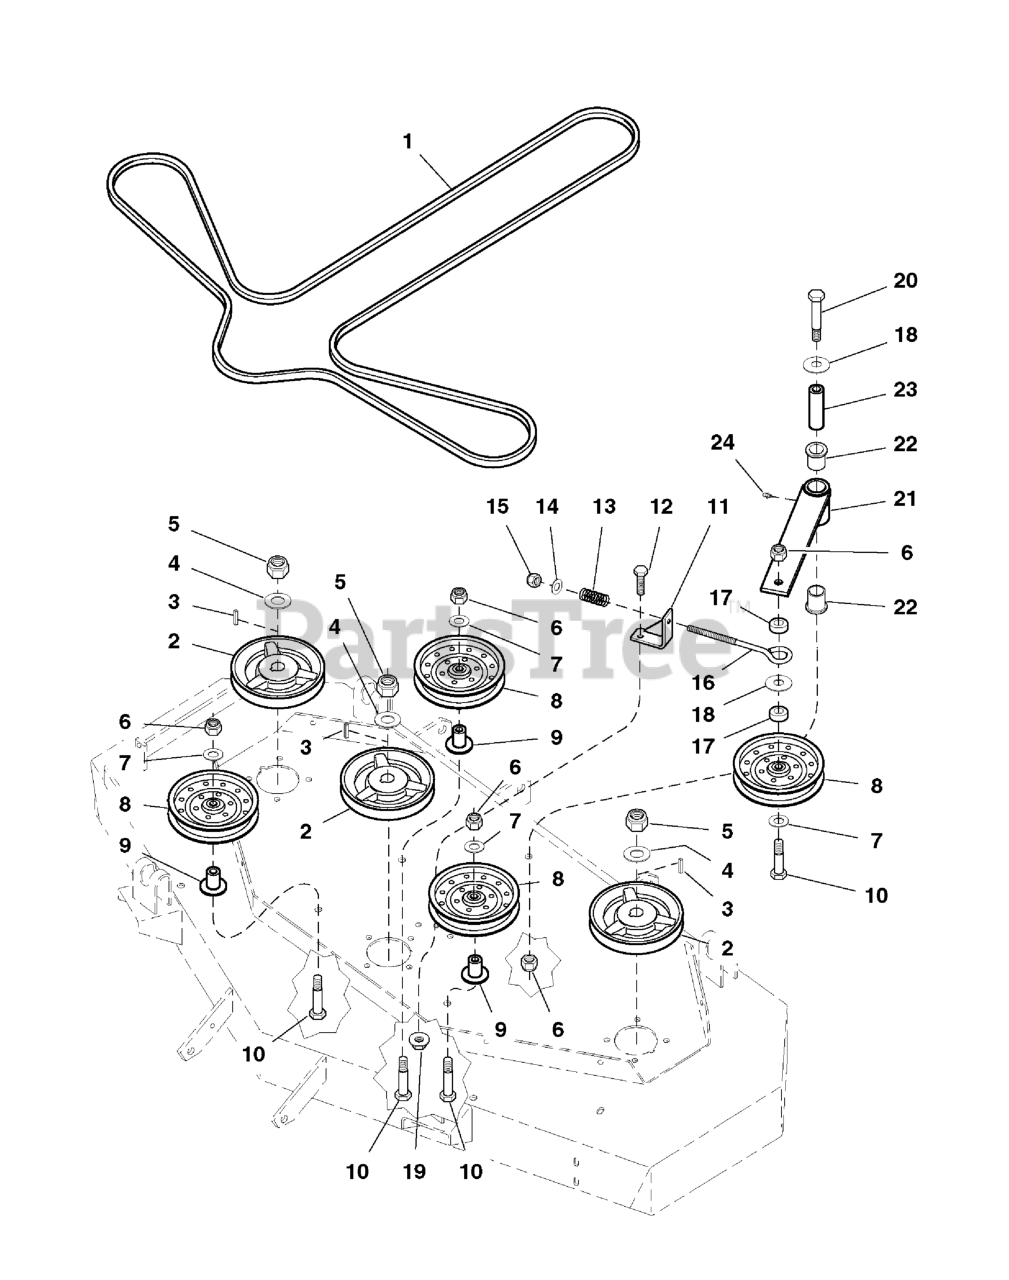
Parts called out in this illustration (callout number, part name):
1	BELT, 61" Deck
2	SPINDLE PULLEY
3	KEY, 1/4 SQ. X 1-1/4
4	WASHER, Spring
5	NUT, 5/8-18 Hex Nylon Lock
6	NUT, 1/2-13 HEX NYLON LOCK
7	WASHER, 1/2 SAE
9	IDLER MOUNT
10	BOLT, 1/2-13 X 3" GD5 CZ
11	SPRING ANCHOR
12	BOLT, 3/8-16 X 1" GD5 CZ
13	SPRING, Compression
14	WASHER, 3/8 SAE
15	NUT, 3/8-16 HEX NYLON LOCK
16	EYEBOLT, 3/8" x 8"
17	SPACER, .52 x 1.00 x .44
18	WASHER, 1/2" USS
19	NUT, 3/8-16 Hex Serrated Flange
20	BOLT, 1/2-13 x 4-1/2
21	IDLER ARM
22	BUSHING, FLANGE
23	SPACER, .52 x 1.00 x 3.50
24	GREASE FITTING
